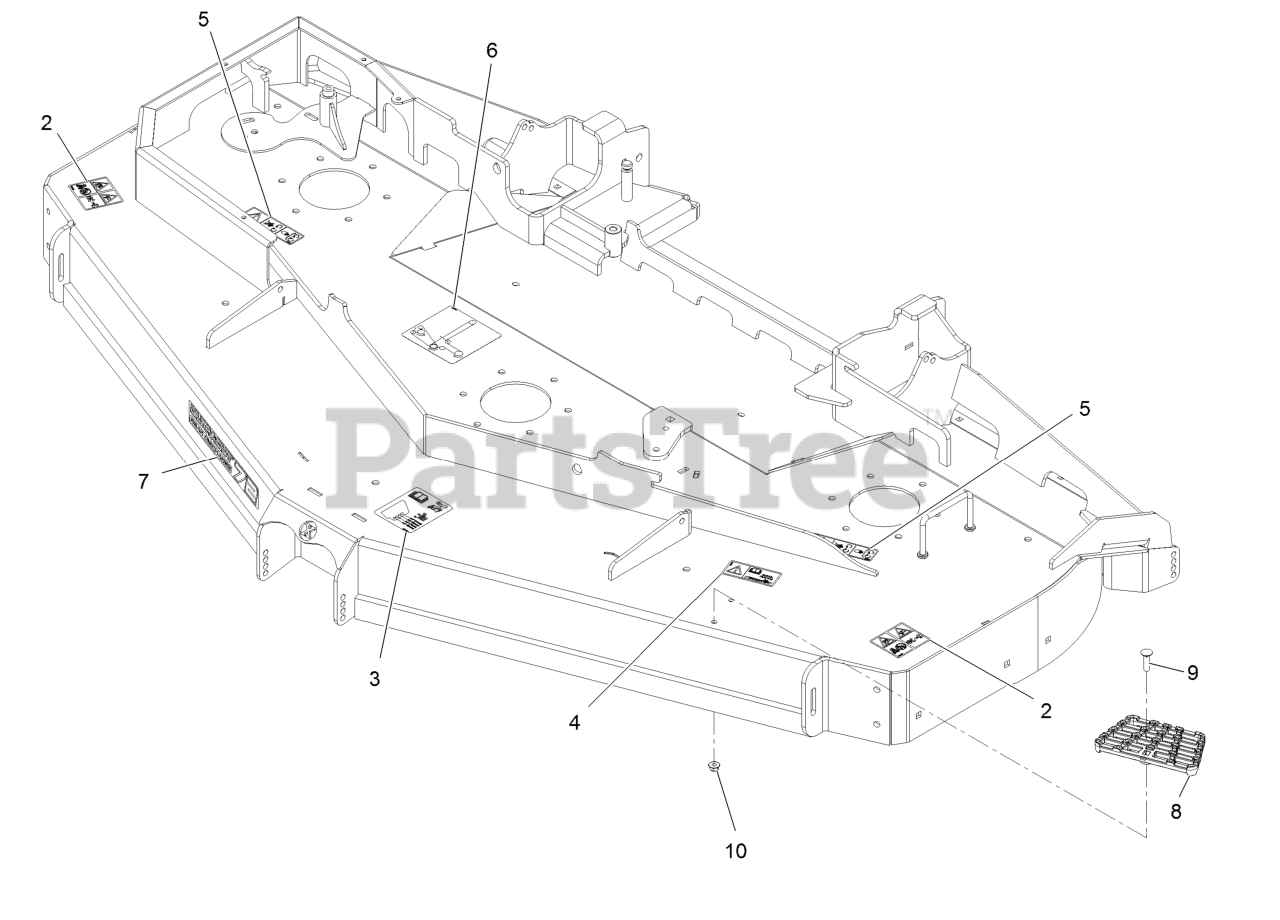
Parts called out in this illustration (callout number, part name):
2	Decal-Danger, Thrown Object
3	Decal-Roller, Anti-Scalp
4	Decal-Bolt Torque
5	Decal-Cover, Missing
6	Decal-Routing, Belt
7	Decal, 72Rd
8	Step-Deck
9	Bolt-Carriage 5/16-18 X 1 1/4
10	Nut-Nyloc 5/16-18 Flg
